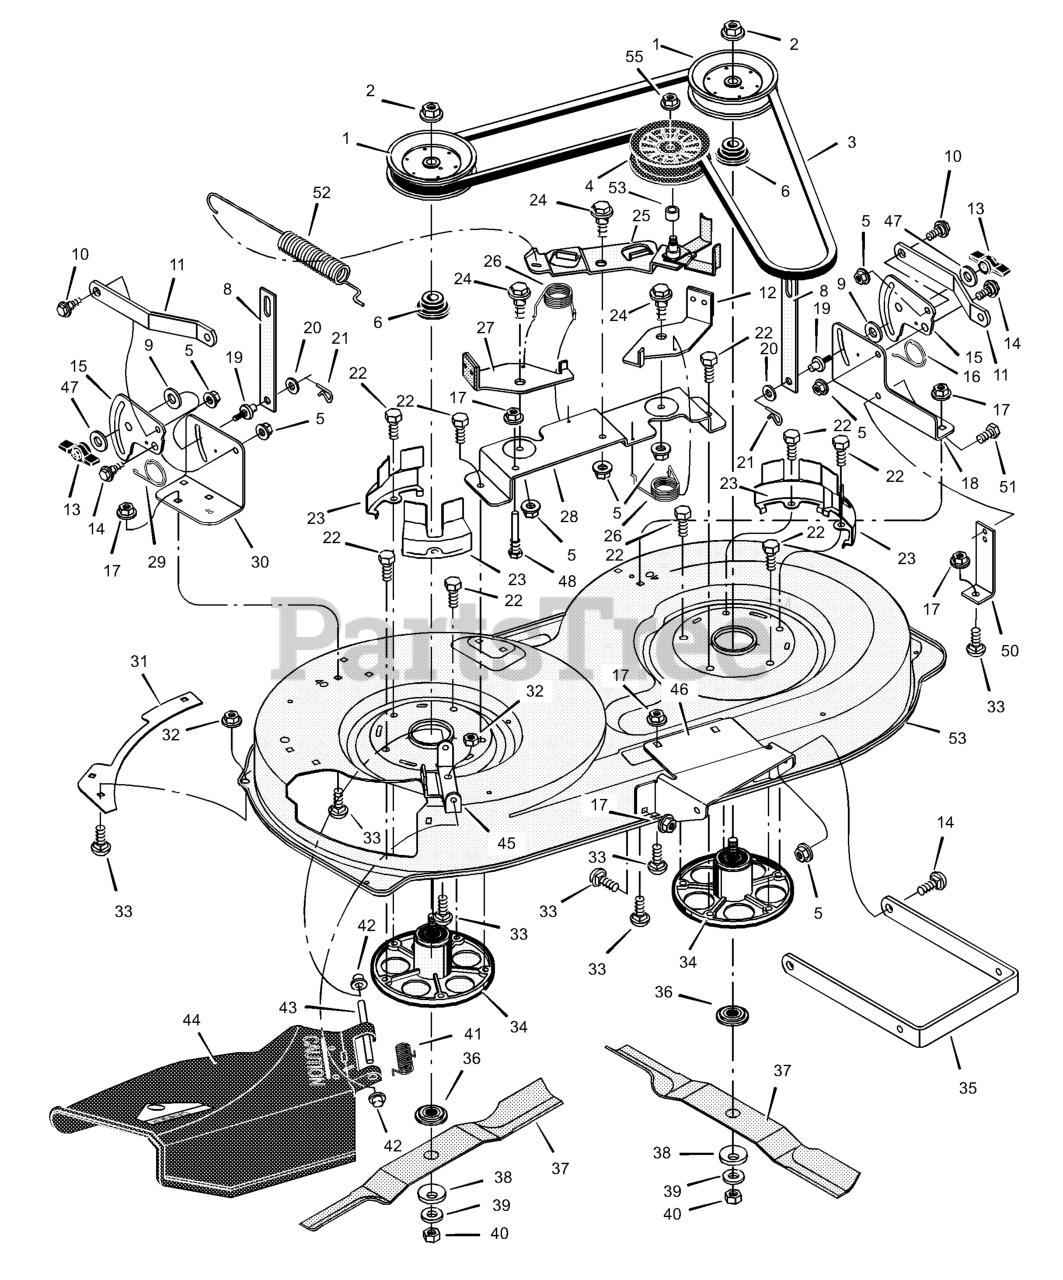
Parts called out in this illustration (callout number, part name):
1	Pulley, Jackshaft
2	Nut, Hex
3	Belt, Mower Drive
4	Pulley, Idler
5	Nut, Flange
6	Spacer, Pulley
8	Link, Lift
9	Pad, Friction
10	Bolt, Shoulder
11	Bracket, Suspension
12	Pad Assembly, Left Brake
13	Knob
14	Bolt, Shoulder
15	Plate, Suspension
17	Nut, Flange
18	Bracket, Suspension
19	Pin, Hanger
21	Pin, Cotter
22	Bolt
23	Cover, Pulley
24	Bolt, Shoulder
25	Arm, Idler
27	Pad Assembly, Right Brake
28	Bracket Assembly, Brake
30	Bracket, Suspension
31	Plate
32	Nut, Flange
33	Bolt, Carriage
34	Mandrell
35	Bracket, Suspension
36	Adapter, Blade
42	Cap, Push On
43	ROD, Deflector
44	Deflector Assembly
45	Bracket, Deflector
46	Bracket, Front Hanger
48	Guide, Belt
50	Bracket, Support
52	Spring, Extension
54	Housing, Blade
55	Nut, Flange
